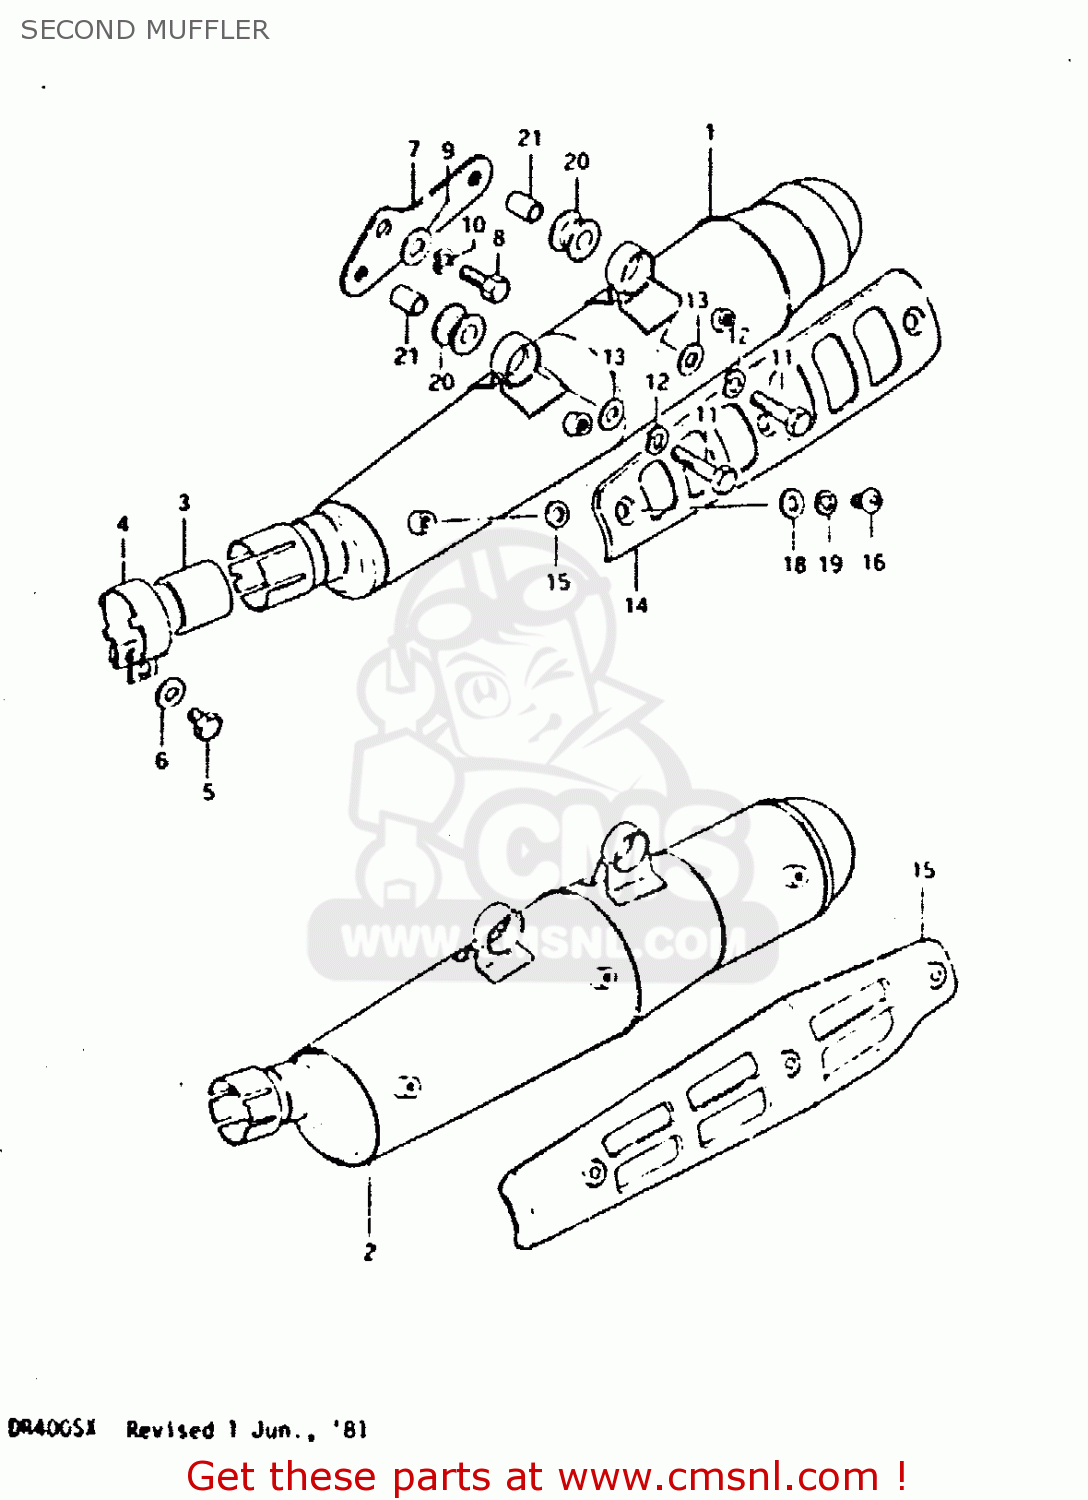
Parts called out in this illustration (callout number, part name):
1	MUFFLER, 2ND
3	CONNECTOR,MUFFLER
4	CLAMP,MUFFLER CONNECTOR
5	BOLT 8X35
6	WASHER
7	BRACKET, MUFFLER HANGER
8	BOLT 10X20
9	WASHER
10	LOCK WASHER
11	BOLT
12	LOCK WASHER
13	WASHER
14	COVER, 2ND MUFFLER
16	SCREW 6X12
17	GASKET 6.2X12X1.5 (MCA)
18	WASHER
19	LOCK WASHER
20	CUSHION
21	SPACER (8.2X12X17)
